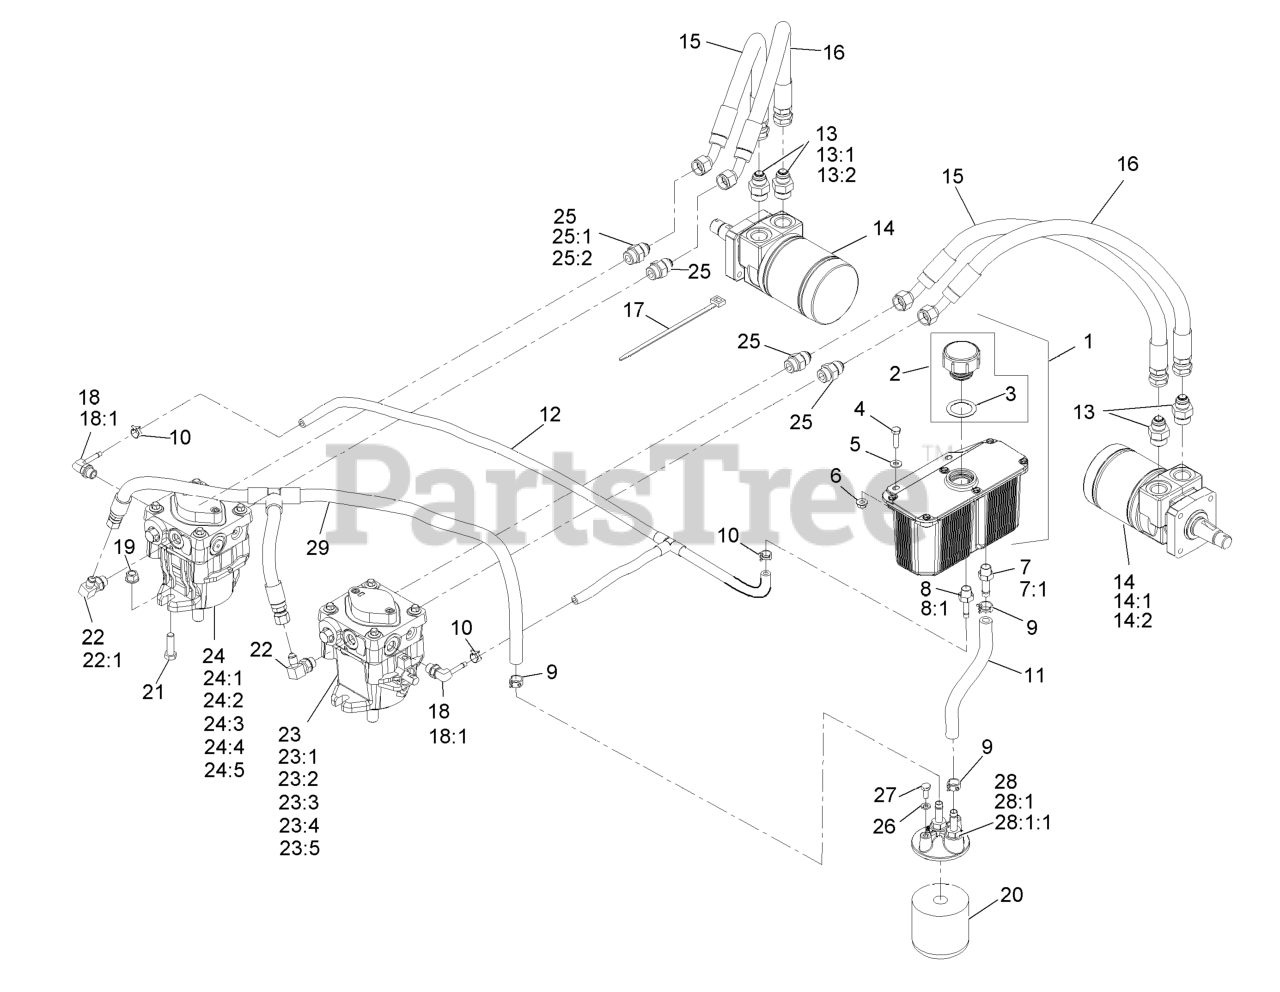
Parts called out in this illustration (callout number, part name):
1	HYD RESERVOIR ASM
2	KIT,HYD RES CAP W/GASKET
3	GASKET-CAP
4	SCREW-HH
5	WASHER-FLAT
7	ADAPTER-STRAIGHT
8	ADAPTER-STRAIGHT
9	CLAMP-HOSE
10	CLAMP-HOSE
11	HOSE,CASE DRAIN RH
12	HOSE-CASE DRAIN ASM
13	FITTING-STRAIGHT
14	HYD MOTOR ASM
14:1	SEAL KIT
14:2	BEARING AND SEAL KIT
15	HOSE,HYDRAULIC W/COVER
16	HOSE,HYDRAULIC W/COVER
17	TIE-PLASTIC
18	ELBOW-90 DEG
19	NUT-FLANGE
20	FILTER-25 MICRON, BI-DIRE
20	ELEMENT-FILTER, WINTER
21	SCREW-HH
22	FITTING-ELBOW, 90 DEG
23	PUMP-HYD PE RH TTH
23:1	INPUT SHAFT KIT
23:2	BEARING-THRUST
23:3	CYLINDER BLOCK KIT
23:4	SEAL OVERHAUL KIT
23:5	KIT, 10CC PUMP KIT
24	PUMP-HYD PE LH TTH
24:1	INPUT SHAFT KIT
24:2	BEARING-THRUST
24:3	CYLINDER BLOCK KIT
24:4	SEAL OVERHAUL KIT
24:5	KIT, 10CC PUMP KIT
25	FITTING-STRAIGHT
26	WASHER-LOCK
27	SCREW-HH
28	FILTER HEAD ASM
28:1	ADAPTER-STRAIGHT
29	ASM,CHARGE HOSE
